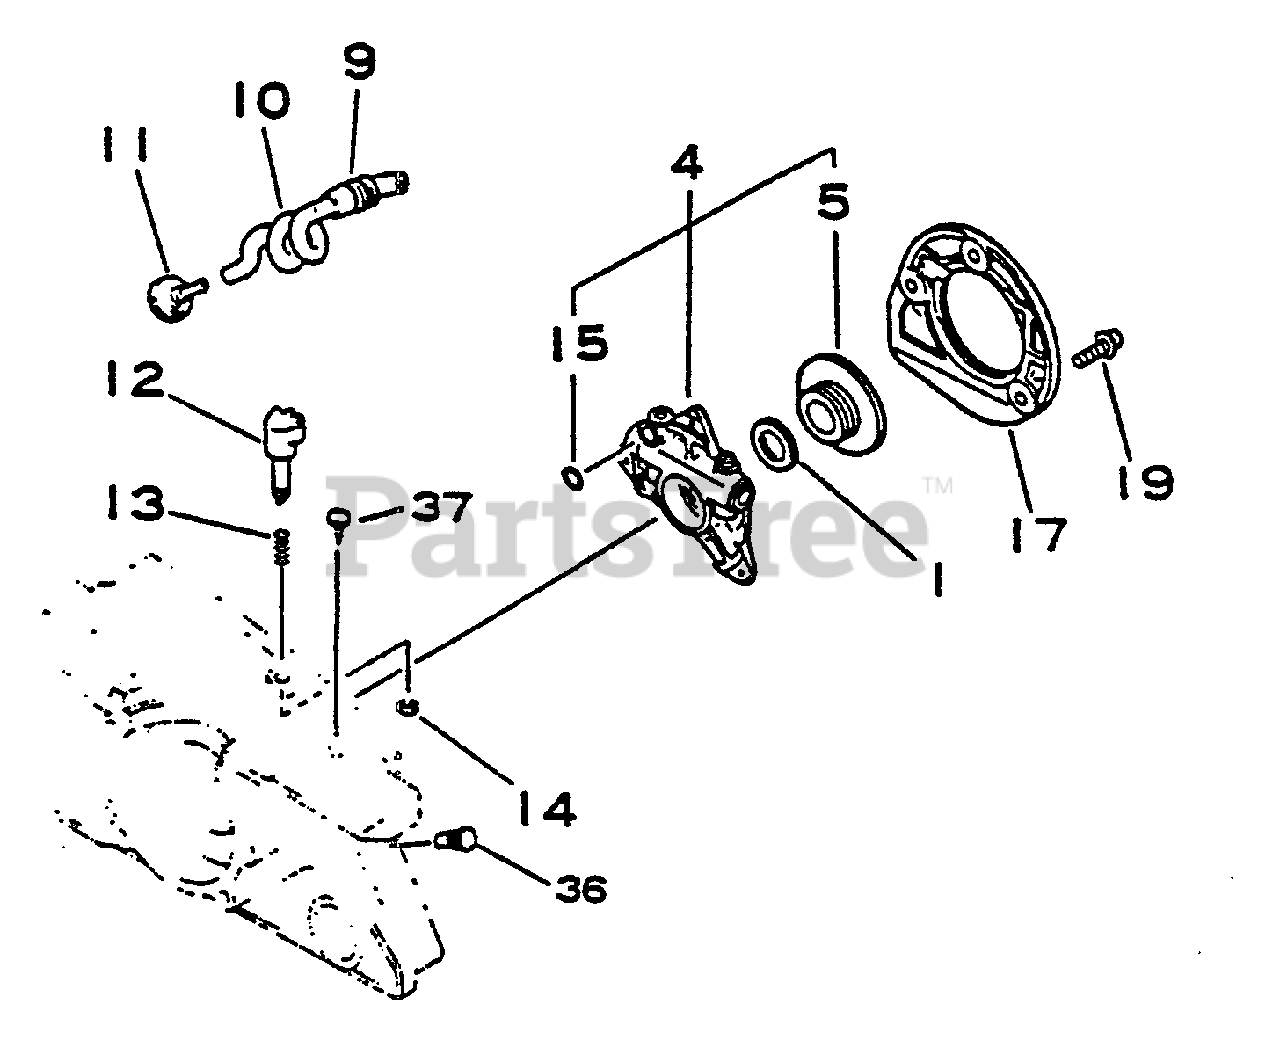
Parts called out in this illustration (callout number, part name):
4	AUTO-OILER ASSY
5	WHEEL, WORM
10	PIPE - OIL
11	FILTER, OIL
12	DIAL, AUTO-OILER
14	RING, RETAINING - 3
15	O-RING - 3
17	COVER, OIL PUMP
19	SCREW - 4X14
36	PLUG
